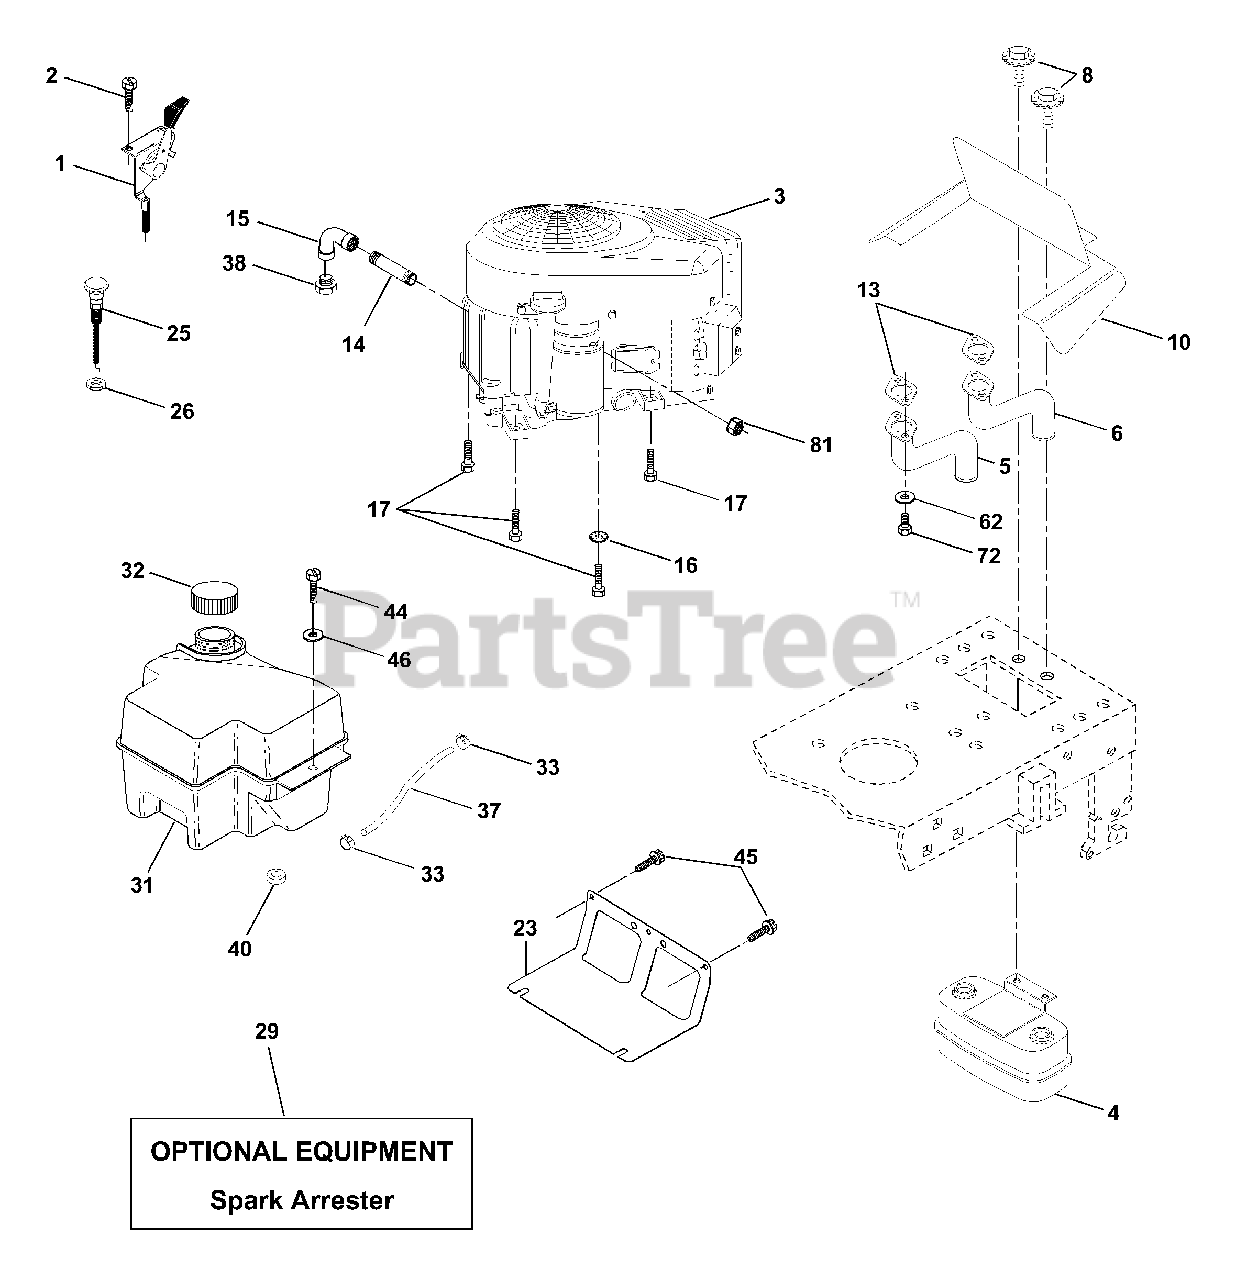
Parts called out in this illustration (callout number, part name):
1	Control Throt
2	Screw Hex Thd Cut 1/4-20x5/8 T
4	Muffler Exhaust
5	Exhaust Asm. Left
6	Exhaust Asm. Right
8	Bolt 5/16-18unc x 3/4 w/sems
10	Shield Heat
13	Gasket Muffler
14	Nipple Pipe 4-12"
15	Elbow Std 90 Degree 3/8-18 Npt
16	Washer Lock Ext Tooth 3/8
17	Screw Thdrol 3/8-16 x 1-1/2 Tytt
23	Shield Brn/Dbr Guard
25	Control Choke
26	Nut Keps 3/8-24 UNF
29	Arrestor Spark
31	Tank Fuel Front 2.00
32	Cap Fuel
33	Clamp Hose Blk
37	Line Fuel
38	Plug Oil Drain
40	Bushing Snap Nyl Blk Fuel Line
44	Screw Hex wsh Thdrol 1/4-20 x 3/4
45	Screw Hex Wsh Thdr 3/8-16 x 3/4
46	Washer 9/32 x 7/8 x 16 Ga.
62	Washer Lock Hvy HLCL Spr 5/16
72	Screw hex Hd Cap 5/16-18 x 3/4
81	Nut Keps Hex 1/4-20 Unc
